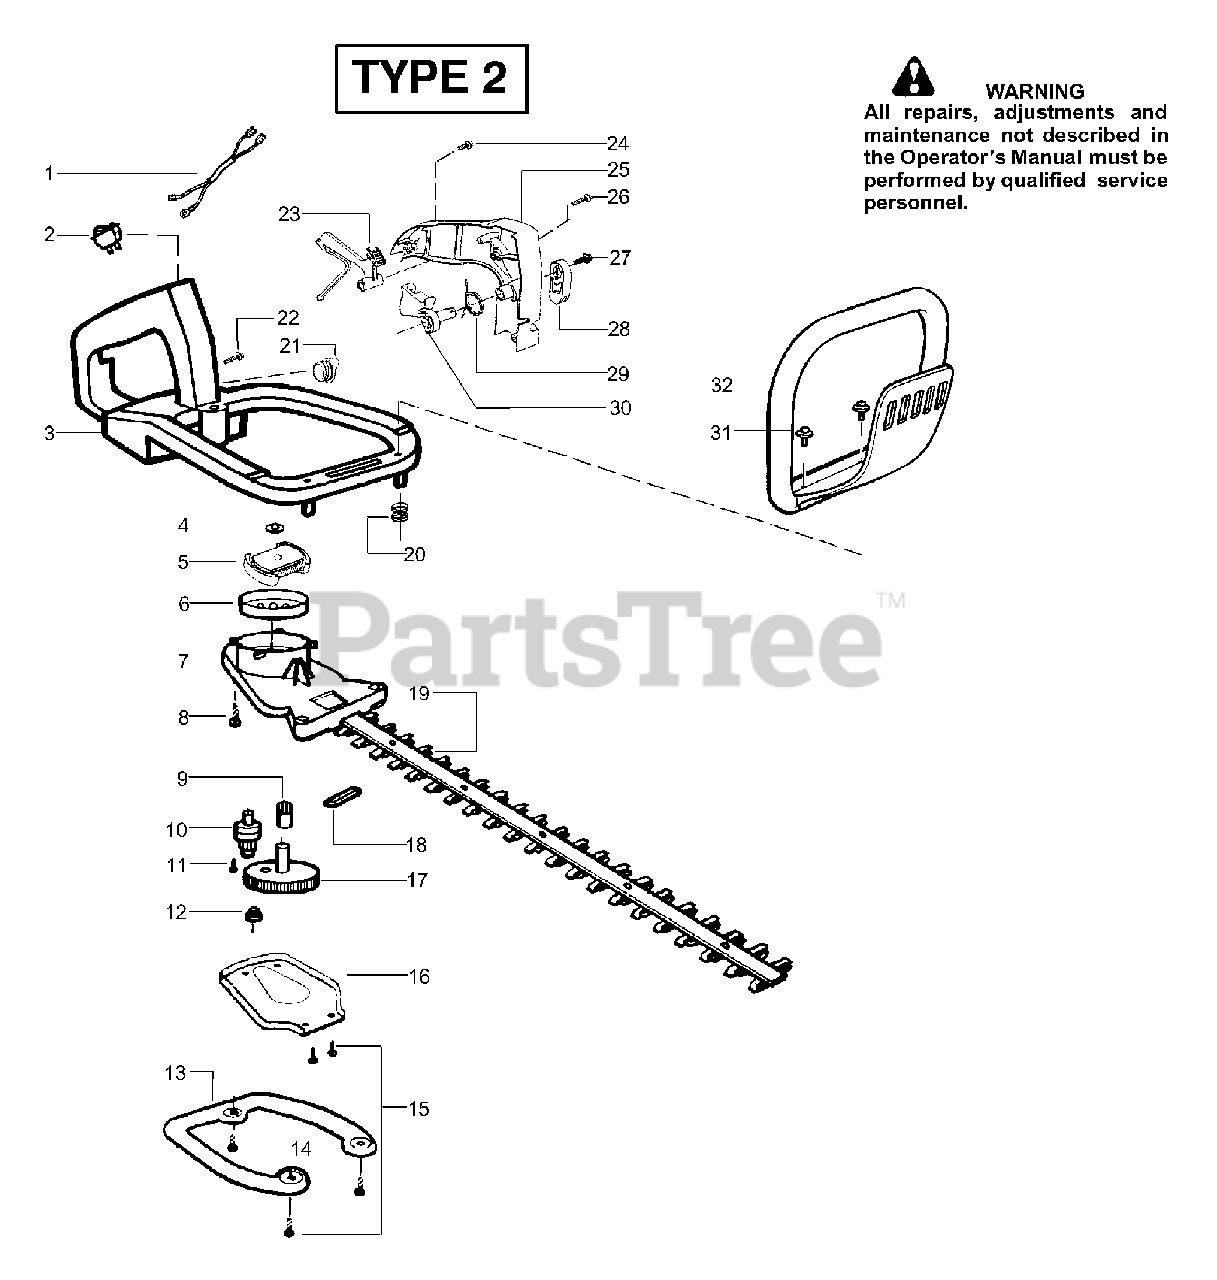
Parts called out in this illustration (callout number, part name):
1	Assy-Leadwire/Switch
2	Switch-Ignition
3	Assy-Rear Handle & Tank
4	Washer-Clutch
5	Kit-Clutch Assy.
6	Assy-Drum
7	Assy-Gear Box
9	Bearing-Gear
10	Assy-Pinion
11	Screw
12	Bushing-Blade
13	Plate-Isolator
16	Cover-Gear Box Plate
17	Kit-Drive Gear Ass'y.
18	Seal-Blade (Felt)
19	Assy-Blade 22"
21	Assy-Fuel Cap
23	Lockout-Throttle
25	Cover-Handle
28	Lever-Trigger
29	Spring-Trigger
32	Handle-Front
